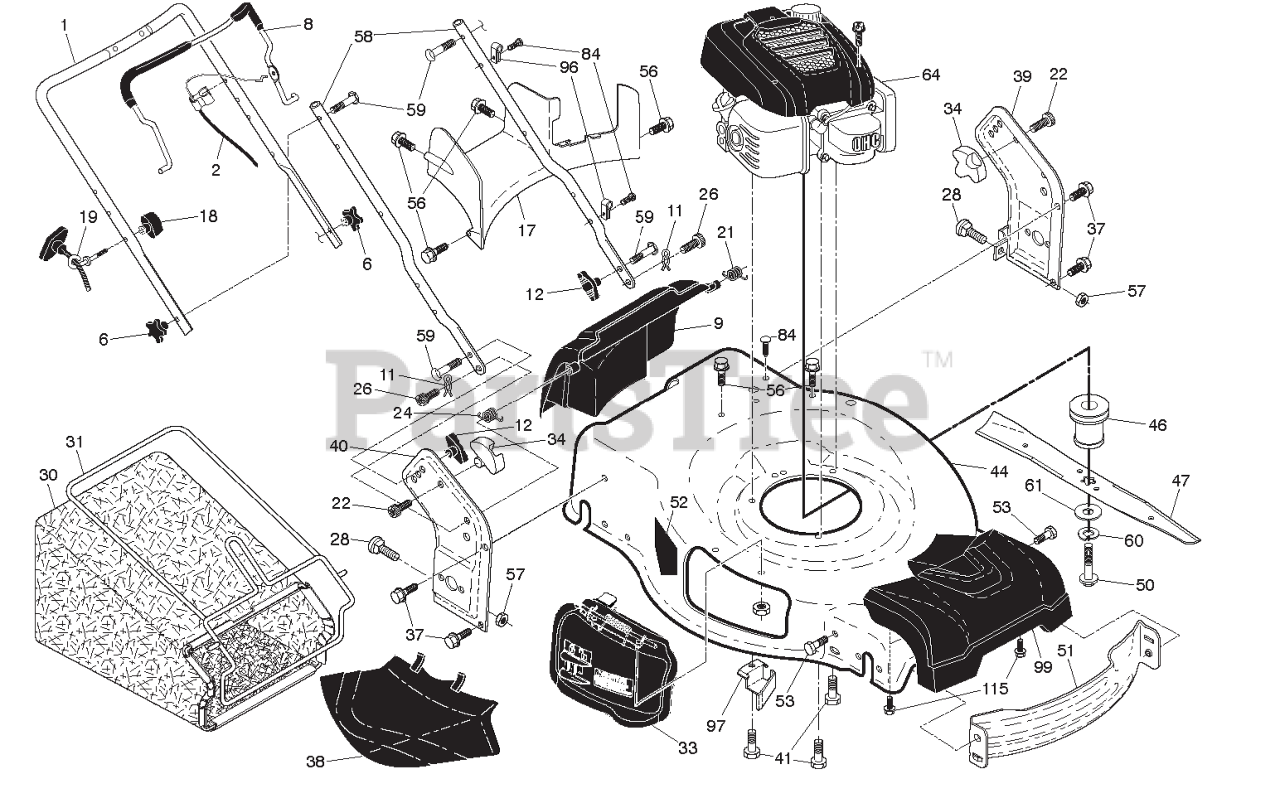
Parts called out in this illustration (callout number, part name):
1	HANDLE.UP.3POS.BS.AW2.GREY
2	CABLE MZR (ZONE) 48.5 CONDUIT
6	KNOB.HANDLE.PLASTIC.STAR.BLACK
8	BAIL.OM.ERGO.BENT.MZR.ORAN.668
9	DOOR.REAR.ASM.22+.HUSQ.F/RG.CE
11	COTTER.HAIRPIN.DOOR/HANDLE.PIV
12	KNOB, DEFLECTOR
17	BAFFLE.REAR.22+RGD.AWD.PLASTIC
18	T-KNOB.NEW ROPE GUIDE
19	GUIDE.ROPE.BLK.ZINC.CHROM
21	SPRING.LH.BLACK
22	SCREW.PAN.HEAD.#10
24	SPRING.RH.GRAY
26	SCREW,DOOR/HANDLE.PIVOT
28	BOLT.CARRIAGE.LN.5/16-18X.5/8
30	GBAG.BA85028ER.GRY/ORG
31	FRAME.GBAG.22+.BLK
33	DOOR ASSY KIT.MULCH DOOR.CE 22
34	BRACKET.GRASSBAG.ATTACHING.BLK
37	BOLT.5/16HEX.WHS.HD
38	DEFLECTOR.CLIPPING.22.BLACK
39	BRACKET.ASM.HANDLE.LT.22+.GREY
40	BRACKET.ASM.HANDLE.RT.22+.GREY
41	BOLT 3/8-16X1-1/8
44	HOUSING.22+RGD.MCUT.WO.HUS.TRI
46	ADAPTER BLADE, 25 MM 22+ AWD/
47	BLADE.22.MULCH.STANDARD
50	SCREW, HEX HD 3/8-24 X 1-3/8
51	BAFFLE.FRONT.22.PLUS
52	DECAL.INTERNATIONL.CUTFINGER
53	BOLT.5/16HEX.WHS.HD
56	SCREW.HX.13X.750
57	NUT.FLANGE.5/16
58	HANDLE.LOWER.ASM.W/PLUG.22+.49
59	BOLT, HANDLE 5/16-18X1.75
60	LOCKWASHER
61	WASHER,HARDEN
84	FASTENER.PUSH.O.250X0.783
96	CLIP.CABLE.BLK
97	BRACKET.BELT.GUIDE.22+.BZP
99	COVER.ASM.FRONT.HUSQ.22+RGD
115	SCREW.HI-LO. 5/16 X 1.00
